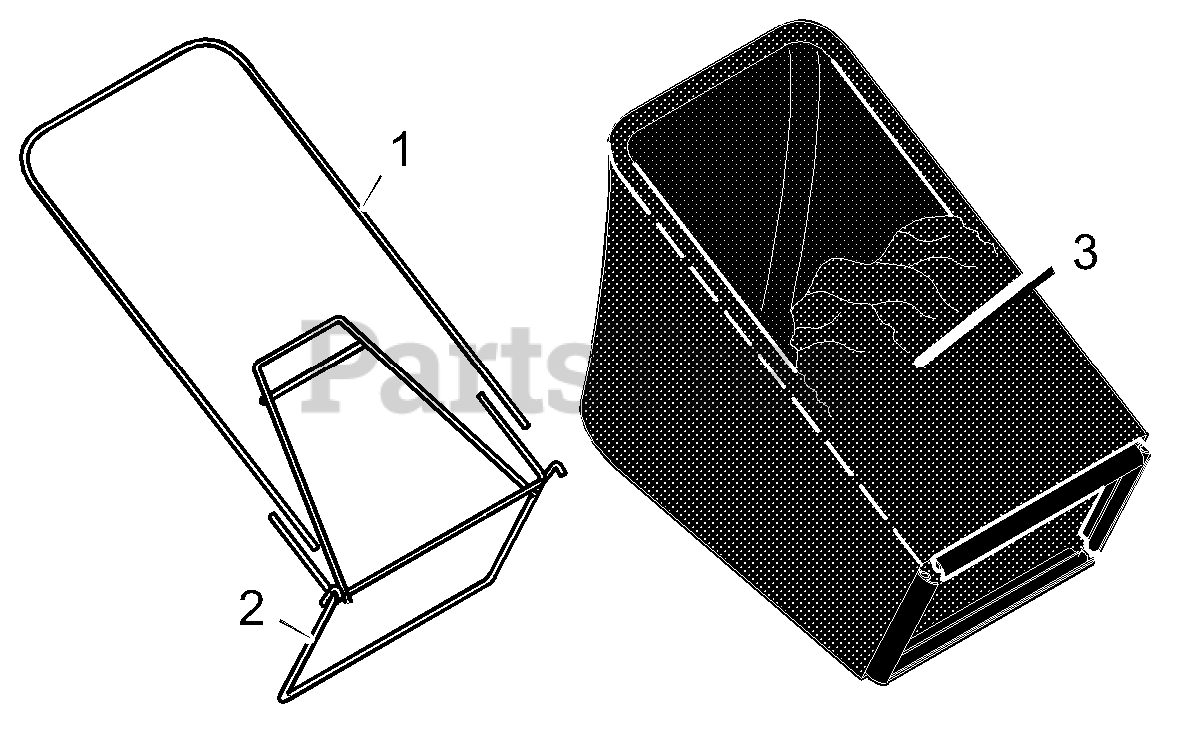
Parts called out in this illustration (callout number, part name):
1	Frame, Top
2	Frame Assy.
3	Bag, Cloth
